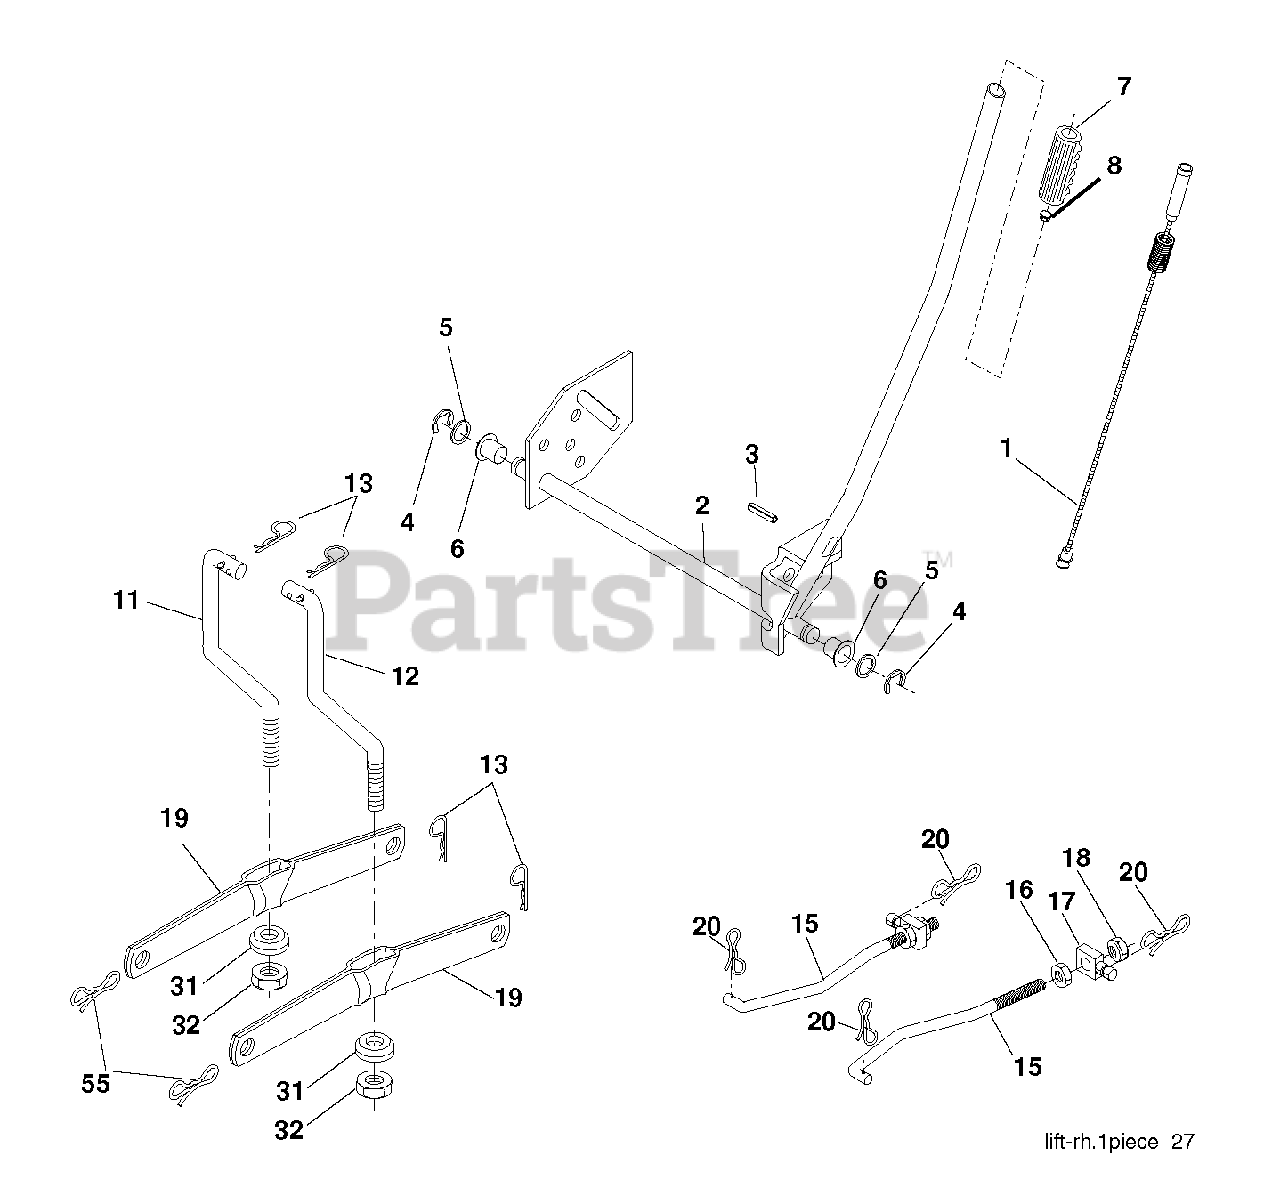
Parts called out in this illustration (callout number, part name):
1	PLUNGER.ASM.LIFT.LVR.BLK.17.32
2	SHAFT ASM R HANDLE
4	RETAINING RING LT
6	BEARING.NYLON
7	GRIP
8	PLUNGER BUT KIT
11	LINK LIFT LH
12	LINK LIFT RH
13	RETAINER-SPRNG RB
15	LINK.SUSPENSION.FRONT
16	NUT
18	NUT
19	ARM.REAR.SUSPENSION
20	PIN.COTTER.7/16.BOW TI
31	BEARING.PIVOT.LIFT
32	NUT CROWNLOCK 3/8-24
55	PIN.COTTER.5/16.BOW TI
